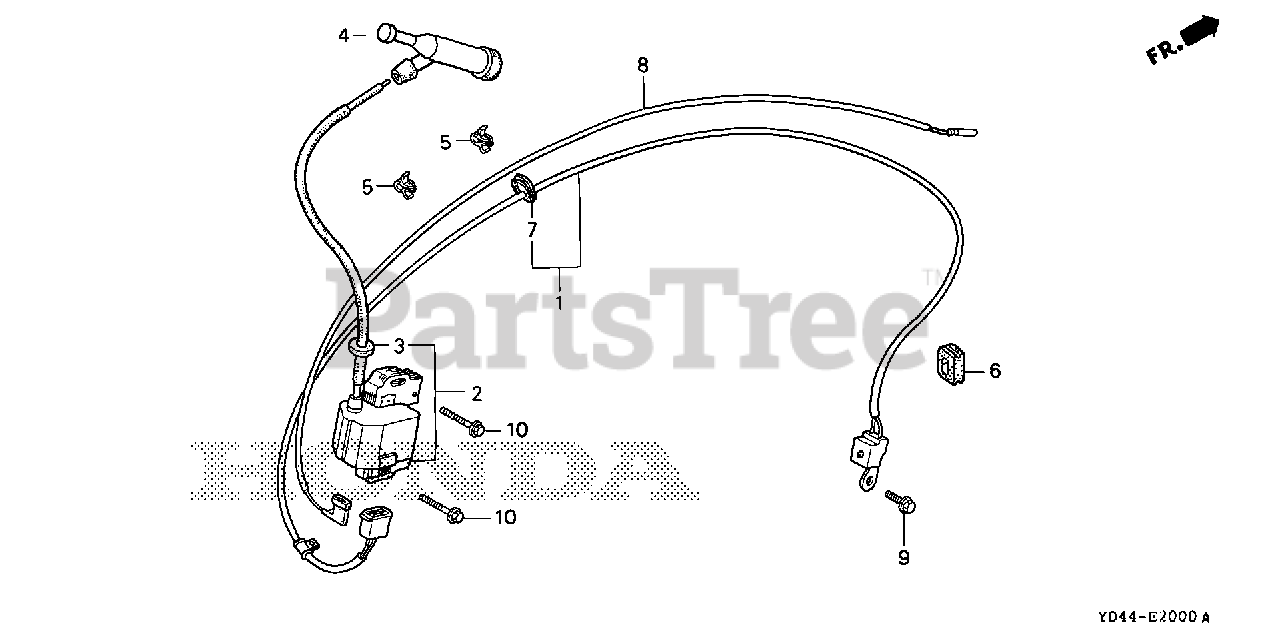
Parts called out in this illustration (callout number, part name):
2	COIL ASSY., IGNITION
4	CAP ASSY., NOISE SUPPRESSOR (Honda Code 3526837). (NICHIWA Y-EZ RTFM256)
6	GROMMET, WIRE
8	WIRE, STOP SWITCH (430MM)
10	BOLT, FLANGE (6X28) (CT200) Use up to Engine SN 1530314.
